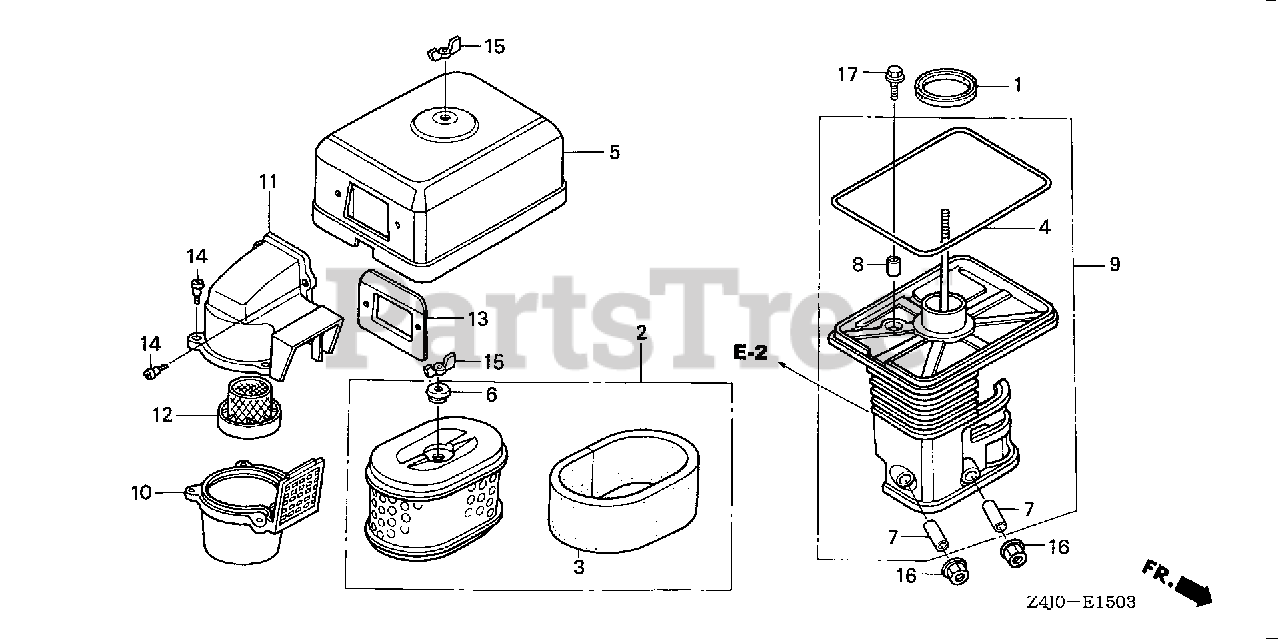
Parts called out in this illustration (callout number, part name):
1	GASKET, ELBOW
2	ELEMENT, AIR CLEANER (DUAL) Use up to Engine SN 2115700.
2	ELEMENT, AIR CLEANER (DUAL)
3	FILTER (OUTER)
4	GASKET, AIR CLEANER COVER
5	COVER, AIR CLEANER (DUAL)
6	GROMMET, AIR CLEANER
7	COLLAR, AIR CLEANER Use from Engine SN 1786085.
8	COLLAR B, AIR CLEANER
9	ELBOW, AIR CLEANER
10	CASE, PRE AIR CLEANER
11	CAP, PRE AIR CLEANER
12	GUIDE, PRE AIR CLEANER
13	PLATE, PRE AIR CLEANER
14	BOLT, MUDGUARD
15	WINGNUT, TOOL BOX SETTING
16	NUT, FLANGE (6MM)
17	BOLT, FLANGE (6X20)
